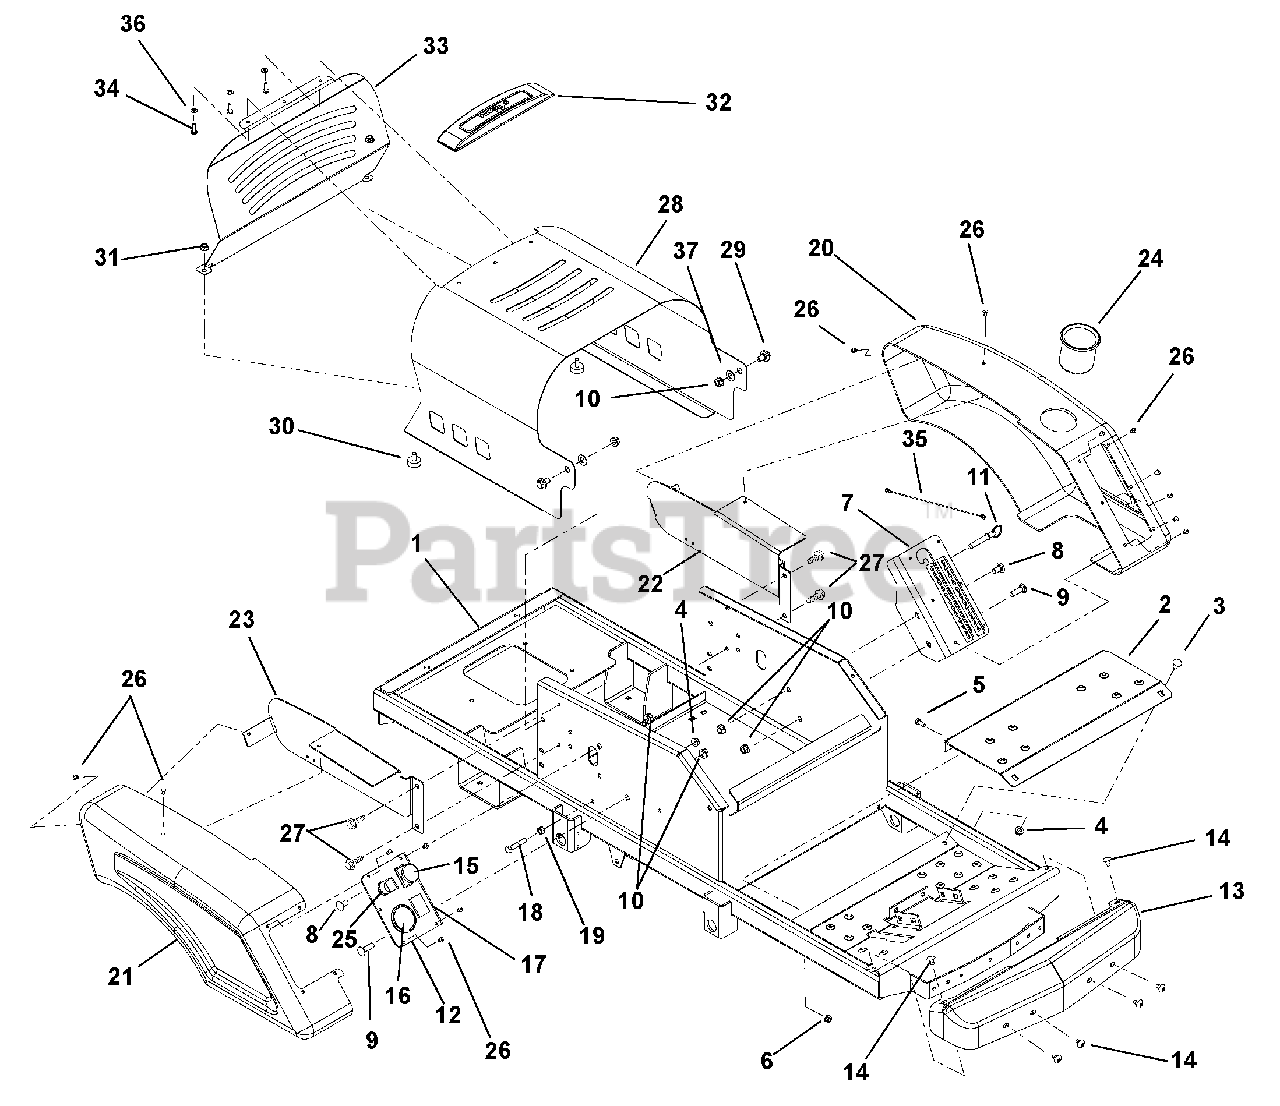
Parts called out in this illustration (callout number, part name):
1	WELDMENT, FRAME
2	FOOTREST
3	@BLT-RHDSSQNK .31-18X.62 G5YZ
4	@NUT-LK-TOP-FLG .31-18 YWZC
5	BLT-HEX .25-20X.63
6	@NUT-LK-TOP-FLG .25-20 YWZC
7	WELDMENT, CUT HEIGHT BRACKET
8	@BLT-RHDSSQNK .38-16X.75 G5YZ
9	@BLT-RDHDSQNK .38-16X1.25 G5YZ
10	@NUT-LK-TOP-FLG .38-16 YWZC
11	PIN, SPRING BALL .375OD X 1.50
12	PANEL, CONTROL (AMP)
13	BUMPER, PLASTIC FRONT
14	SCR-TAP SERRDHDTX .31-18X.50BP
15	SWITCH, CLUTCH
16	METER, AMPERE (-80-0A)
17	METER, BATTERY DISCHARGE 48V
18	@BLT-HEX .31-18X1.75 GR5 YWZC
19	@NUT-HEX .31-18 YWZC
20	FENDER, AMP - LH
21	FENDER, AMP - RH
22	PLATE, FENDER SUPPORT-LH
23	PLATE, FENDER SUPPORT - RH
24	CUPHOLDER
25	SWITCH-IGNITION 2-POS W/KEY
26	RIVET, PLASTIC .195 DIA.
27	@SCR-TAP .31-18X.50 HWH TR YWZ
28	HOOD, AMP
29	BOLT-SHLDR .375-16X.150
30	BUMPER, RUBBER
31	@NUT-SPNLK-FLG .312-18 YWZC
32	TRIM-HOOD, ARIENS SMALL
33	PLATE, BACK HOOD
34	SCREW,PHLPS PAN HEAD 12-11X5/8
35	CABLE, 12.0 LANYARD, NYLON
36	WSHR-FL-STL.250X.500X.049 WYZC
37	WSHR-FL-NYL .518X1.000X.080
